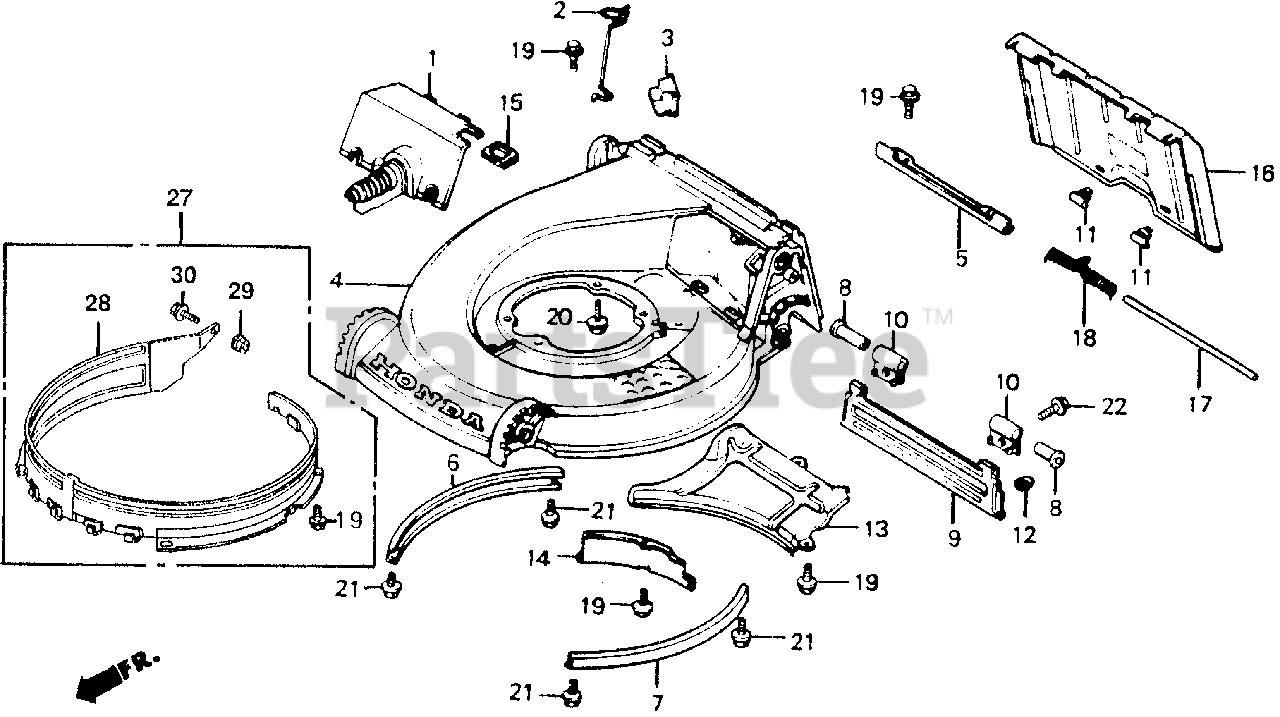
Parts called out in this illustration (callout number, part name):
2	GUIDE, CABLE
3	GROMMET D, CABLE
4	HOUSING, CUTTER
5	HINGE, DISCHARGE GUARD
6	GUARD, R. HOUSING
7	GUARD, L. HOUSING
8	BUSH, SAFETY SHIELD
9	SHIELD, SAFETY
10	HANGER, SAFETY SHIELD
11	STOPPER, DISCHARGE GUARD
13	GUIDE, SCROLL
14	LID, ROTO-STOP COVER
16	GUARD, DISCHARGE
16	GUARD, DISCHARGE *NH105* (MAT BLACK)
17	SHAFT, DISCHARGE GUARD
18	SPRING, GUARD RETURN
19	BOLT, FLANGE (6X12) (CT200)
19	BOLT, FLANGE (6X12) (CT200) Use from Frame SN 1292914.
20	BOLT, ENGINE SETTING
21	BOLT, FLANGE (6X10)
22	BOLT, FLANGE (6X12)
27	LINER KIT (INNER) (PUSH TYPE) Use from Frame SN 1242914.
28	LINER (INNER) (PUSH TYPE) Use from Frame SN 1262914.
29	NUT, FLANGE (6MM) Use from Frame SN 1262914.
30	BOLT, FLANGE (6X16) Use from Frame SN 1262914.
